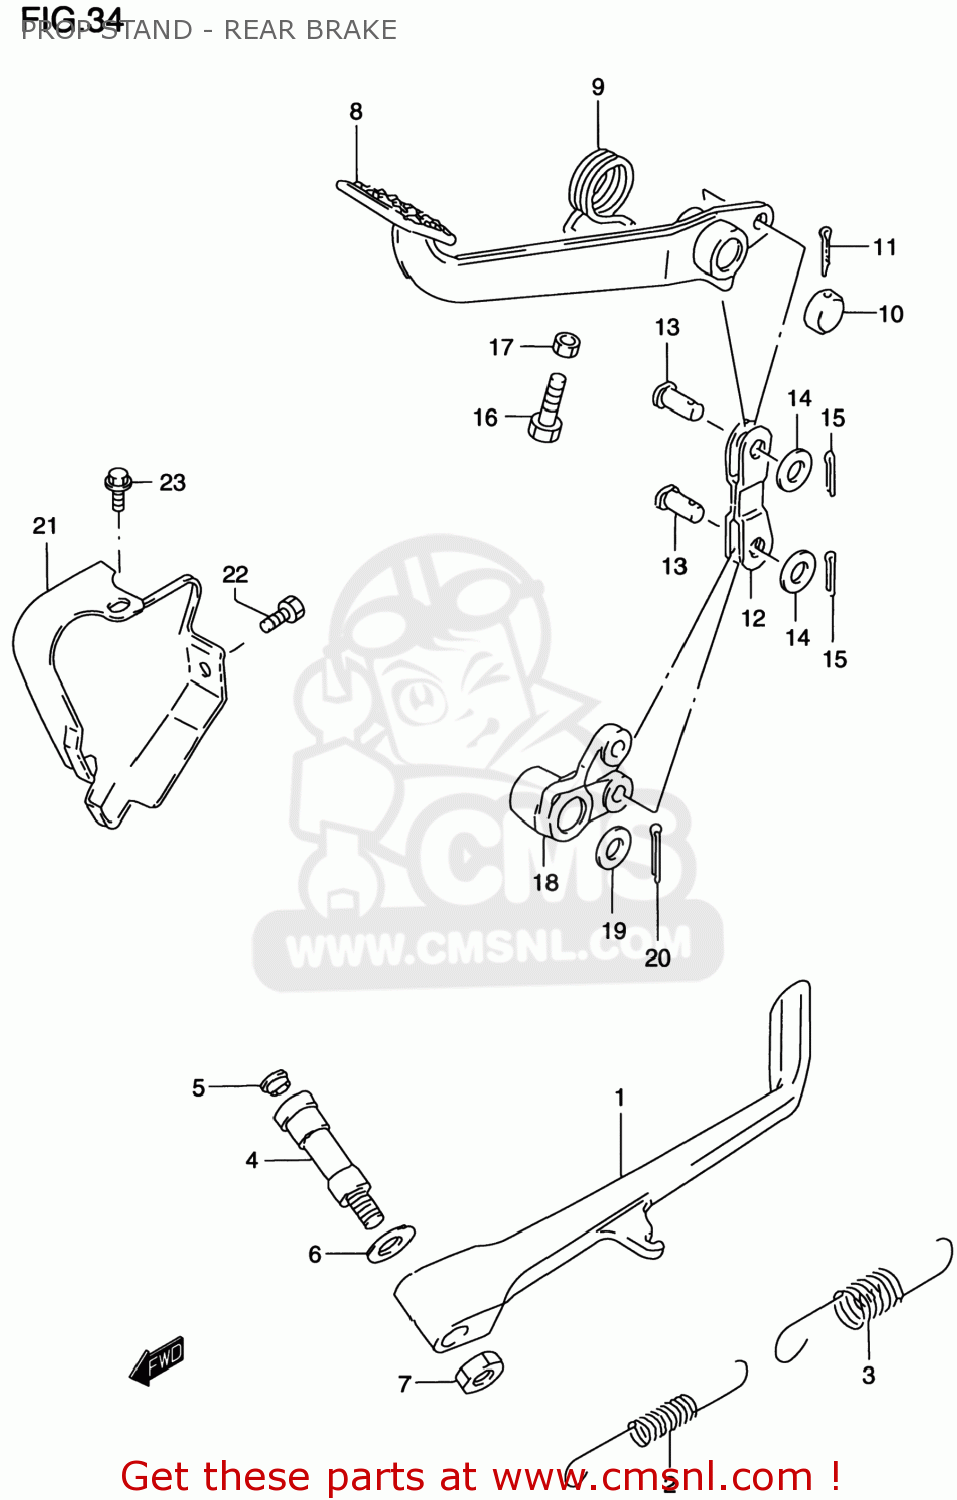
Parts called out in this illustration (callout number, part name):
1	STAND,PROP
2	SPRING
3	SPRING
4	BOLT,PROP STAND
5	CAP
6	SHIM(15X24X0.5)
7	NUT
8	PEDAL ASSY,BRAKE
9	SPRING
10	CAP,BRAKE PEDAL
11	COTTER PIN
12	LINK,BRAKE ROD NO.1
13	PIN
14	WASHER
15	PIN
16	BOLT
17	NUT
18	ARM,BRAKE PEDAL LINK
19	WASHER(16.5X22X1)
20	COTTER PIN
21	COVER,BRAKE
22	SCREW(6X10)
23	BOLT
